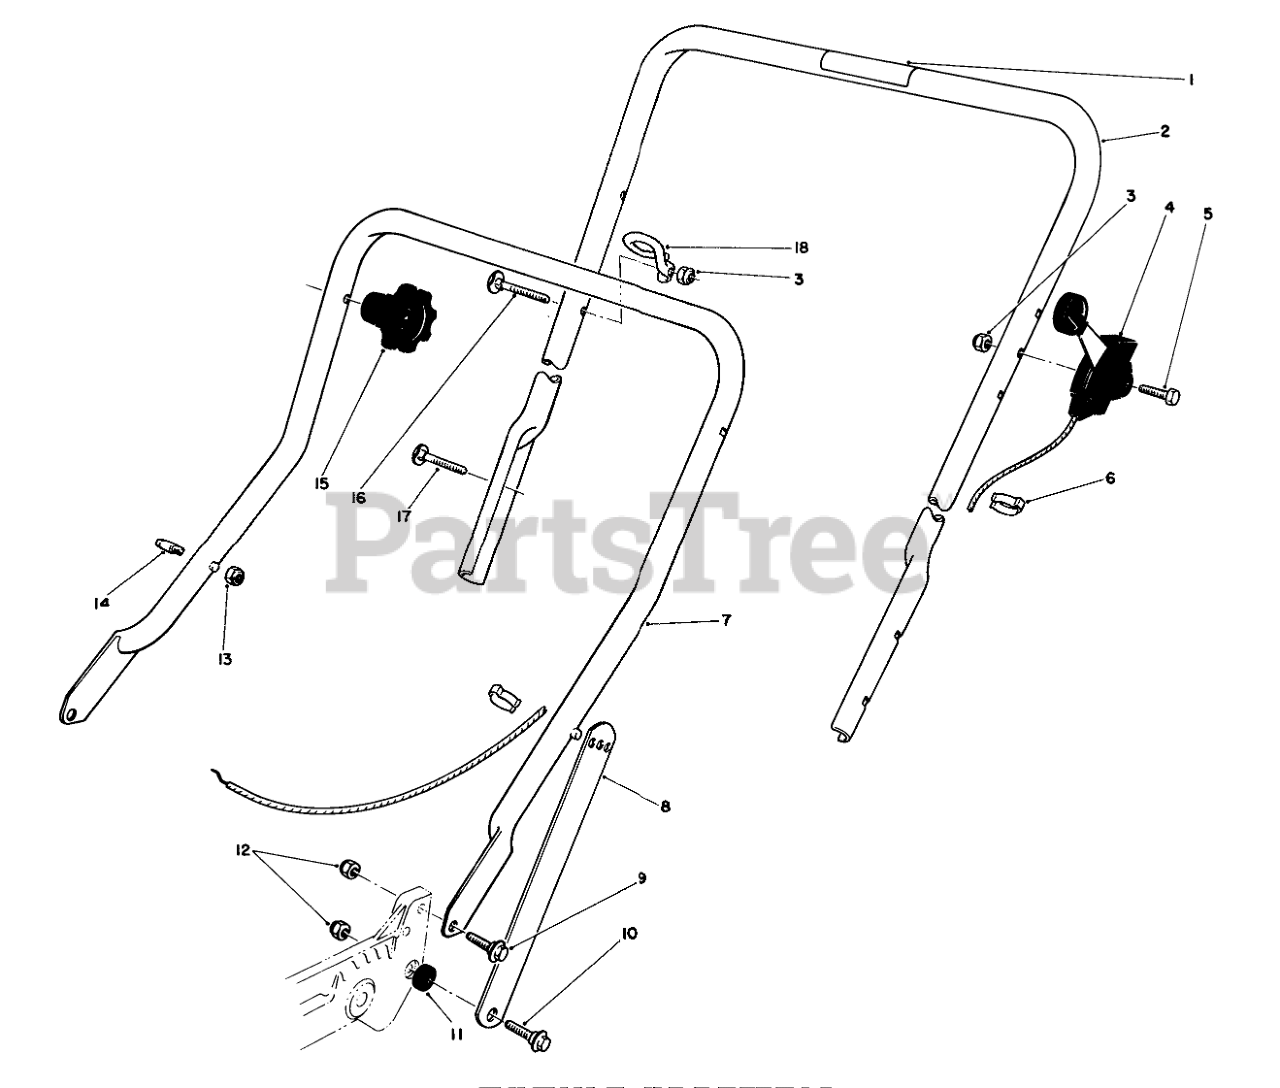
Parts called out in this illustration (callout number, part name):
1	Decal-Danger
2	HANDLE W/DECAL
3	NUT-LOCK, NI
4	THROTTLE CONTROL
5	SCREW-HH
6	BOWDEN CLIP
7	LOWER HANDLE ASM
8	Handle Latch
9	SCREW-SHOULDER
10	SCREW-SHOULDER
11	SPACER
13	NUT-LOCK, NI
14	NUT-LOCK, NI
15	HANDLE PIN
17	HANDLE SCREW
18	5/16-18 X 2 HNDLE SCREW
19	Guide
